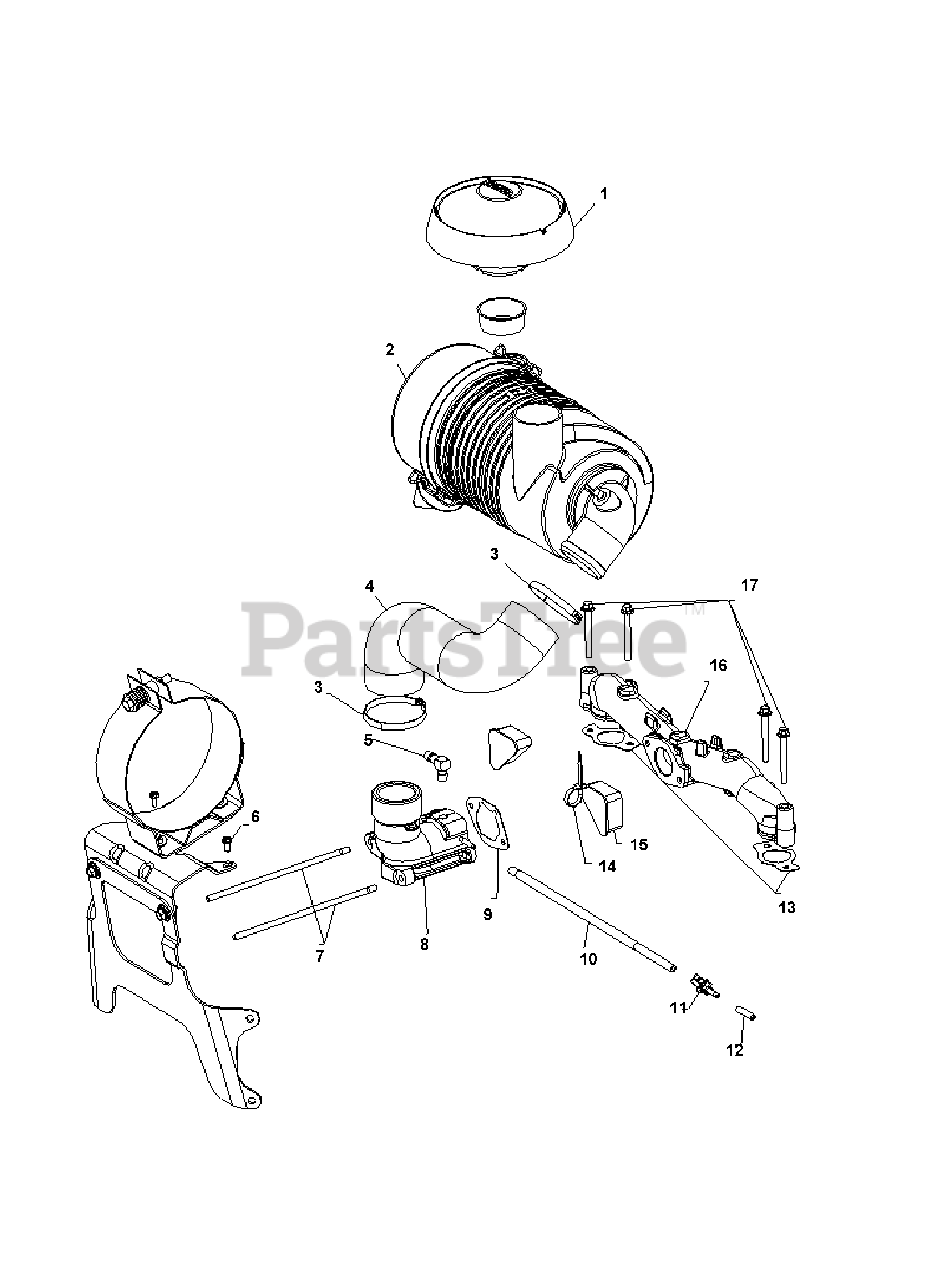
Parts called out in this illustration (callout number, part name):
4	Air Cleaner Hose
5	Hose Connecter
6	Screw, #8-18 x 1/2
7	Stude, M6 x 1.0 x 180
9	Air Cleaner Base Gasket
10	Evaporative Hose
11	Evaporative Connector
13	Intake Manifold Gasket
15	Blower Housing Cover
16	Intake Manifold
17	Screw, M6 x 1.0 x 55
